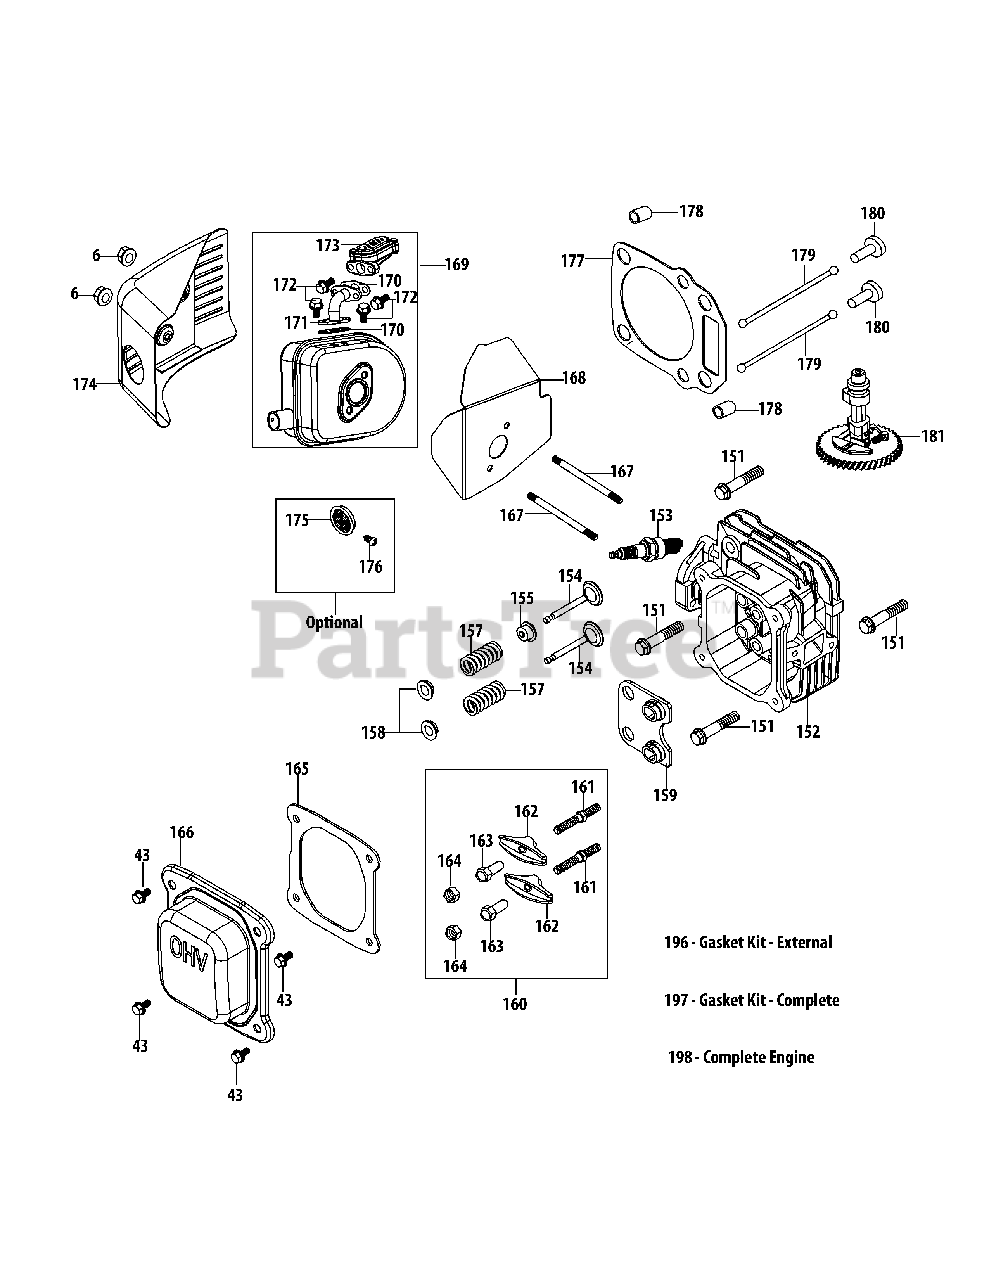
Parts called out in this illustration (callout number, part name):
6	Nut M6X10
43	Bolt M6X14
151	Bolt M8X54
152	Cylinder Head Asm
152	Cylinder Head Svc Kit
153	Spark Plug
155	Intake Valve Seal
157	Valve Spring
158	Valve Spring Retainer
159	Push Rod Guide
160	Rocker Arm Assembly
161	Rocker Arm Stud
162	Rocker Arm
163	Fulcrum Nut
165	Valve Cover Gasket
166	Valve Cover
167	Muffler Stud M6X95
167	Muffler Stud Assemlby
168	Muffler Gasket
169	Muffler Assembly
170	Secondary Air Valve Gasket
171	Secondary Air Tube
172	Bolt M6×12
173	Secondary Air Valve
174	Muffler Shield
175	Spark Arrestor
176	Spark Arrestor Screw
177	Cylinder Head Gasket
178	Cylinder Head Dowel Pin 10×16
181	Camshaft Assembly
196	Gasket Kit - External
197	Gasket Kit - Complete
198	Complete Engine
